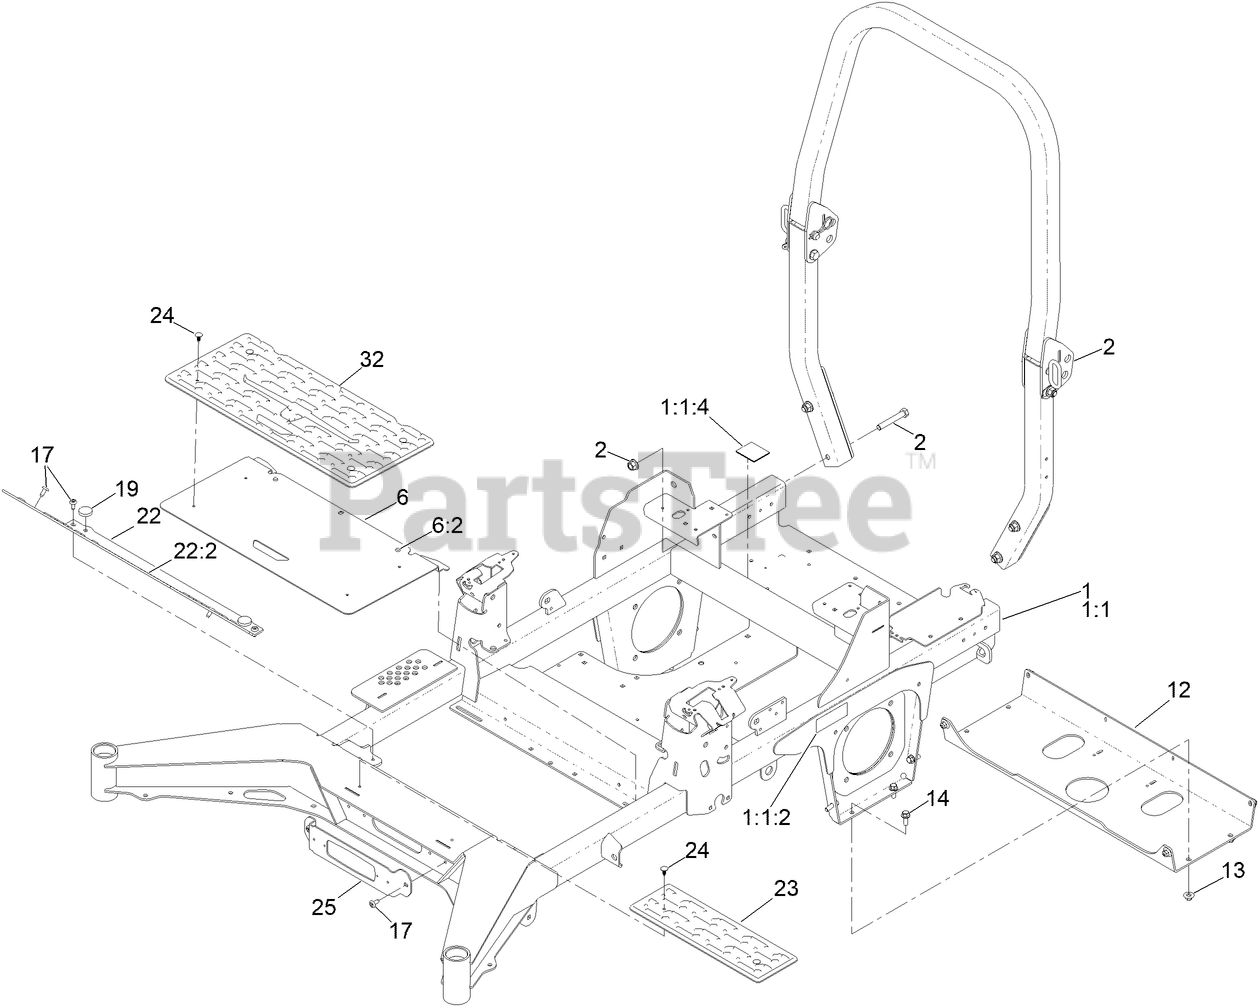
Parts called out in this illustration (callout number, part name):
1	FRAME ASM
1:1	FRAME-72 XL
1:1:2	DECAL-WARNING
1:1:4	DECAL, BELT ROUTING
2	ASM-ROPS
6	ASM-FLOOR PAN
6:2	BUMPER-PUSH-IN, RUBBER
12	PLATE-HYDRO
13	NUT-FLANGE, NI
14	SCREW-HHF
19	BUMPER-PUSH-IN, RUBBER
22	TOEBOARD
22:2	DECAL-DANGER
24	PLUG-PLASTIC
25	BRACKET-LIGHT
32	FLOORMAT-FIXED SEAT
